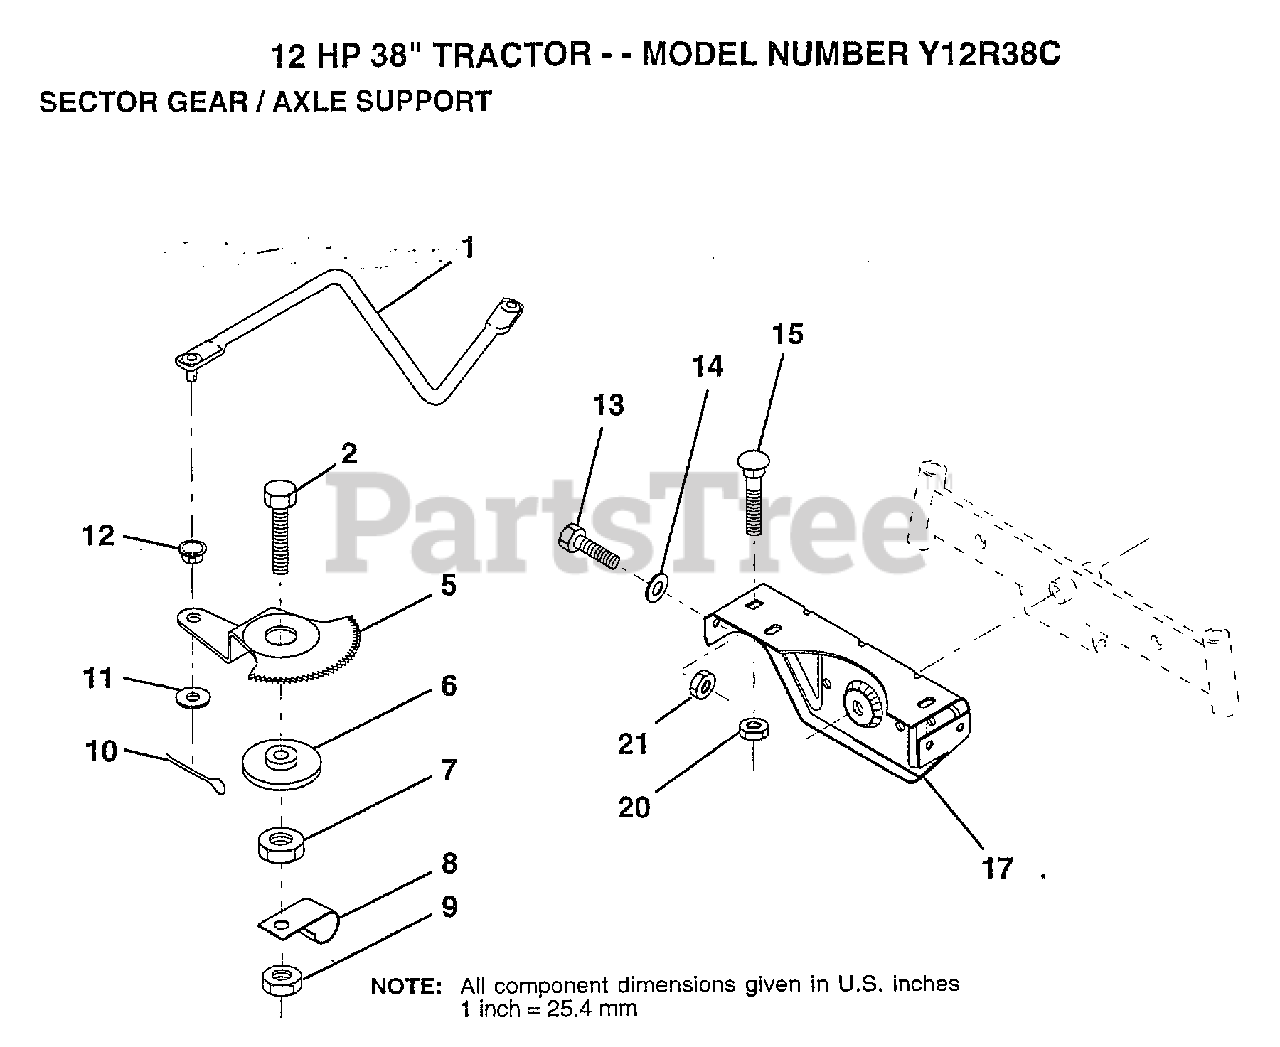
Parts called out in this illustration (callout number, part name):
1	DRAG LINK
2	"BOLT,HEX"
5	GEAR SECTOR
6	BUSHING
7	NUT
8	CLIP INSULATOR
9	NUT LTV
10	COTTER PIN
11	WASHER
12	BUSHING.DRAGLINK
13	BOLT
14	WASHER
15	BOLT
17	SUPT AXLE FRONT
20	NUT
21	NUT
